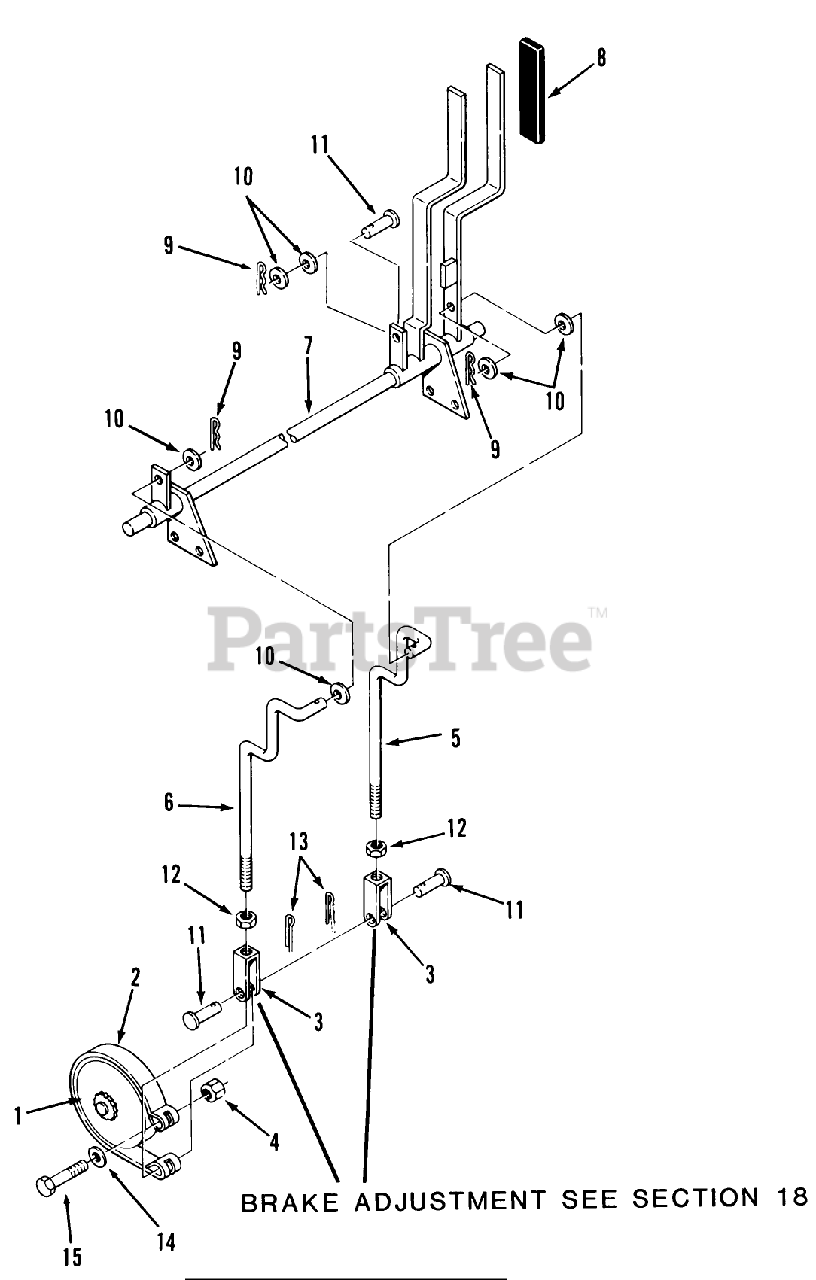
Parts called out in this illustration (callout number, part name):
3	Threaded Yoke
8	GRIP BRAKE20258-K
9	HAIRPIN
